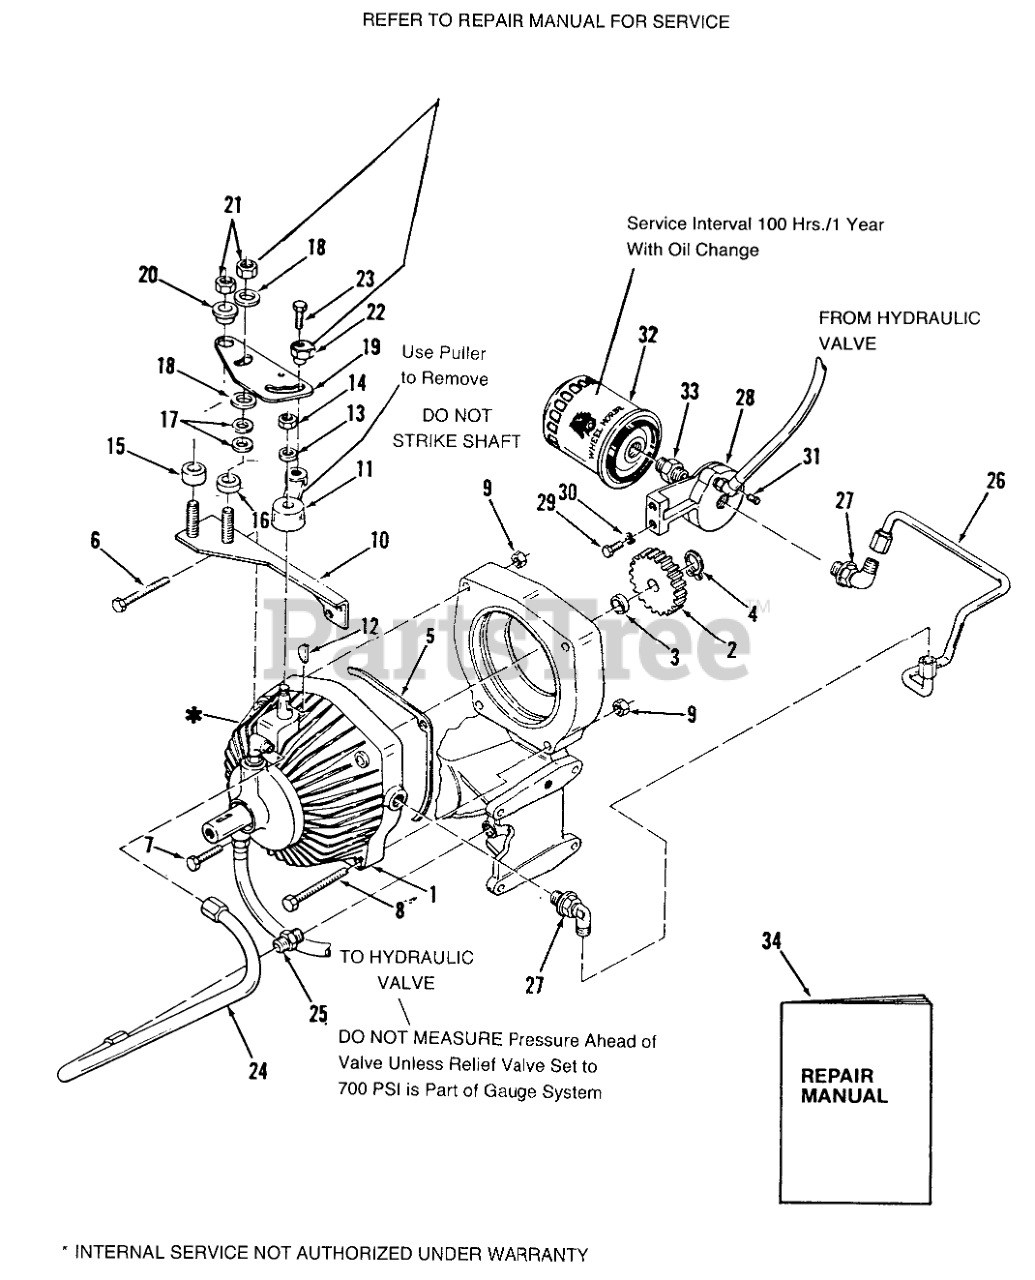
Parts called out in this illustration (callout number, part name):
1	Pump & Motor
2	GEAR 20 TEETH DRIVE
3	SPACER GEAR
4	SNAP RING- 5/8 EXT
5	GASKET
6	Hex Bolt
7	Bolt
8	Bolt 3/8-16 x 6 1/2
9	NUT
10	ASSY-PLATE B
11	ARM-SPEED CONTROLB
12	Key #5 Woodruff
13	Washer
14	Nut
15	SPACER-PIVOT
16	SPACER-FRICTION
17	WASHER-SPRING DISC
18	FRICTION WASHER
19	CAM-SPEED CONTROL (NS)
20	CAM-SPACER
23	Bolt
24	ASSY-TUBE SUCTION
25	FITTING-TUBE
26	ASM-TUBE FILTER OUTL
27	ELBOW
28	BASE-FILTER
29	Bolt
30	Lockwasher
31	PLUG 1/4 PIPE ALLEN
32	Filter-Oil
33	FITTING
34	Repair Manual
